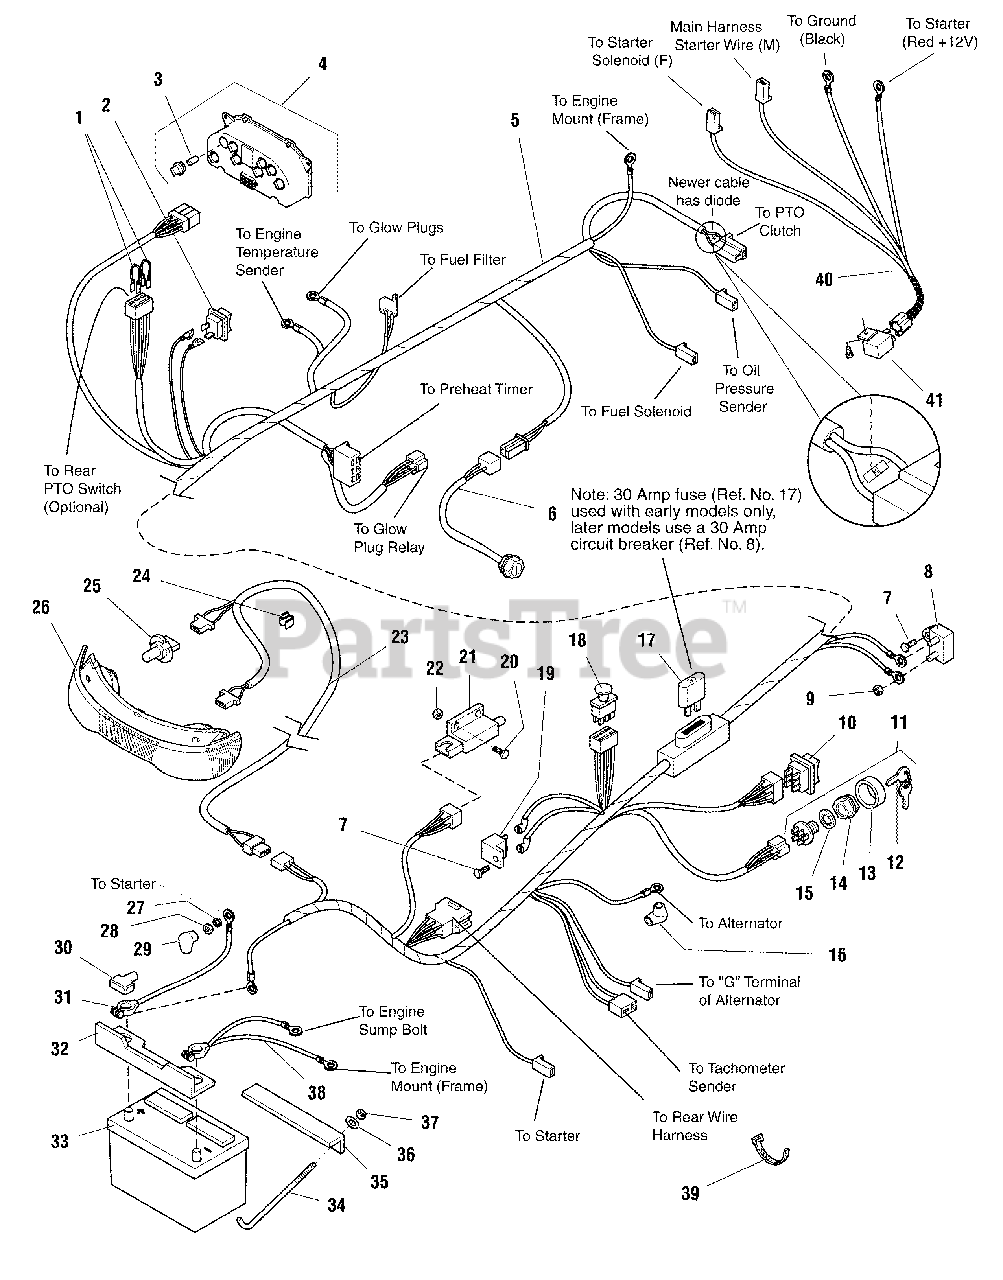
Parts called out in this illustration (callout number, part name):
1	JUMPER
2	SWITCH, Headlights
3	BULB, Instrument Panel
4	INSTRUMENT PANEL, Diesel
5	WIRE HARNESS, Main
6	HARNESS, Power Outlet
7	FASTENER, Panel
8	CIRCUIT BREAKER, 30 Amp
9	NUT, Hex Flange, #10-32
10	SWITCH, Mower Height Adjust
11	ASSEMBLY, Switch & Key
12	KEYS (Set of 2)
13	COVER, Key Switch
14	NUT, Hex Flange, 5/8
15	WASHER, Internal Tooth, 5/8
16	COVER, Terminal
17	FUSE, 30 Amp, Automotive
18	SWITCH, Front PTO
19	BREAKER, Circuit
20	CAPSCREW, #10-24 x 5/8
21	SWITCH, Interlock (NO/NO)
22	NUT, Hex Lock, #10-24
23	HARNESS, Headlight
25	BULB, Headlight, Halogen
26	BEZEL, Headlight
27	LOCKWASHER, 5/16
28	NUT, Hex Jam, M8-1.25, Yellow
29	COVER, Starter Terminal
30	COVER, Positive Battery Terminal
31	CABLE, Battery to Starter
32	GUARD, Battery
33	BATTERY (500 CCA)
34	ROD, Battery Hold-Down
35	BRACKET, Battery
36	WASHER, Plain, 1/4
37	NUT, Hex, Nylon Lock, 1/4-20
38	CABLE, Battery to Ground
40	WIRE HARNESS, Diesel Starter
41	RELAY, 12V 5 Blade
